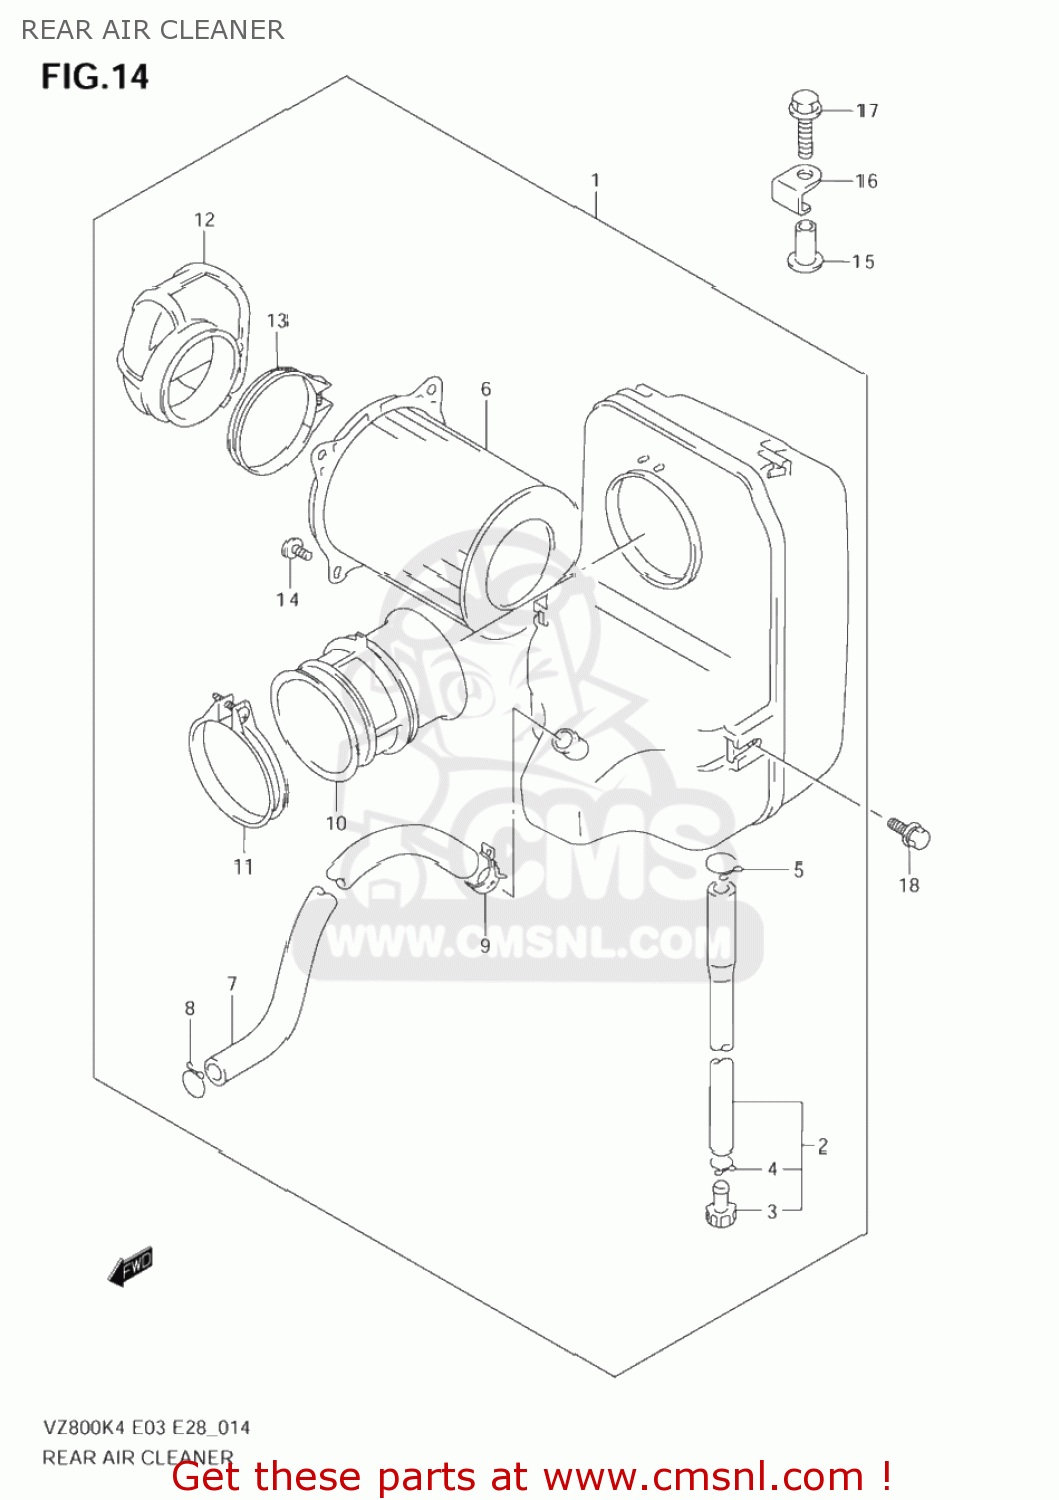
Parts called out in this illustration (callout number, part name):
1	CLEANER ASSY,AIR RR
2	TUBE,DRAIN
3	STOPPER,DRAIN
4	CLIP
5	CLIP
6	FILTER ASSY
7	TUBE,BREATHER
8	CLIP
9	CLIP
10	TUBE,OUTLET
11	CLAMP
12	TUBE,INLET
13	CLAMP
14	SCREW
15	SPACER,AIR CLEANER RR
16	PLATE,AIR CLEANER RR
17	BOLT
18	BOLT
